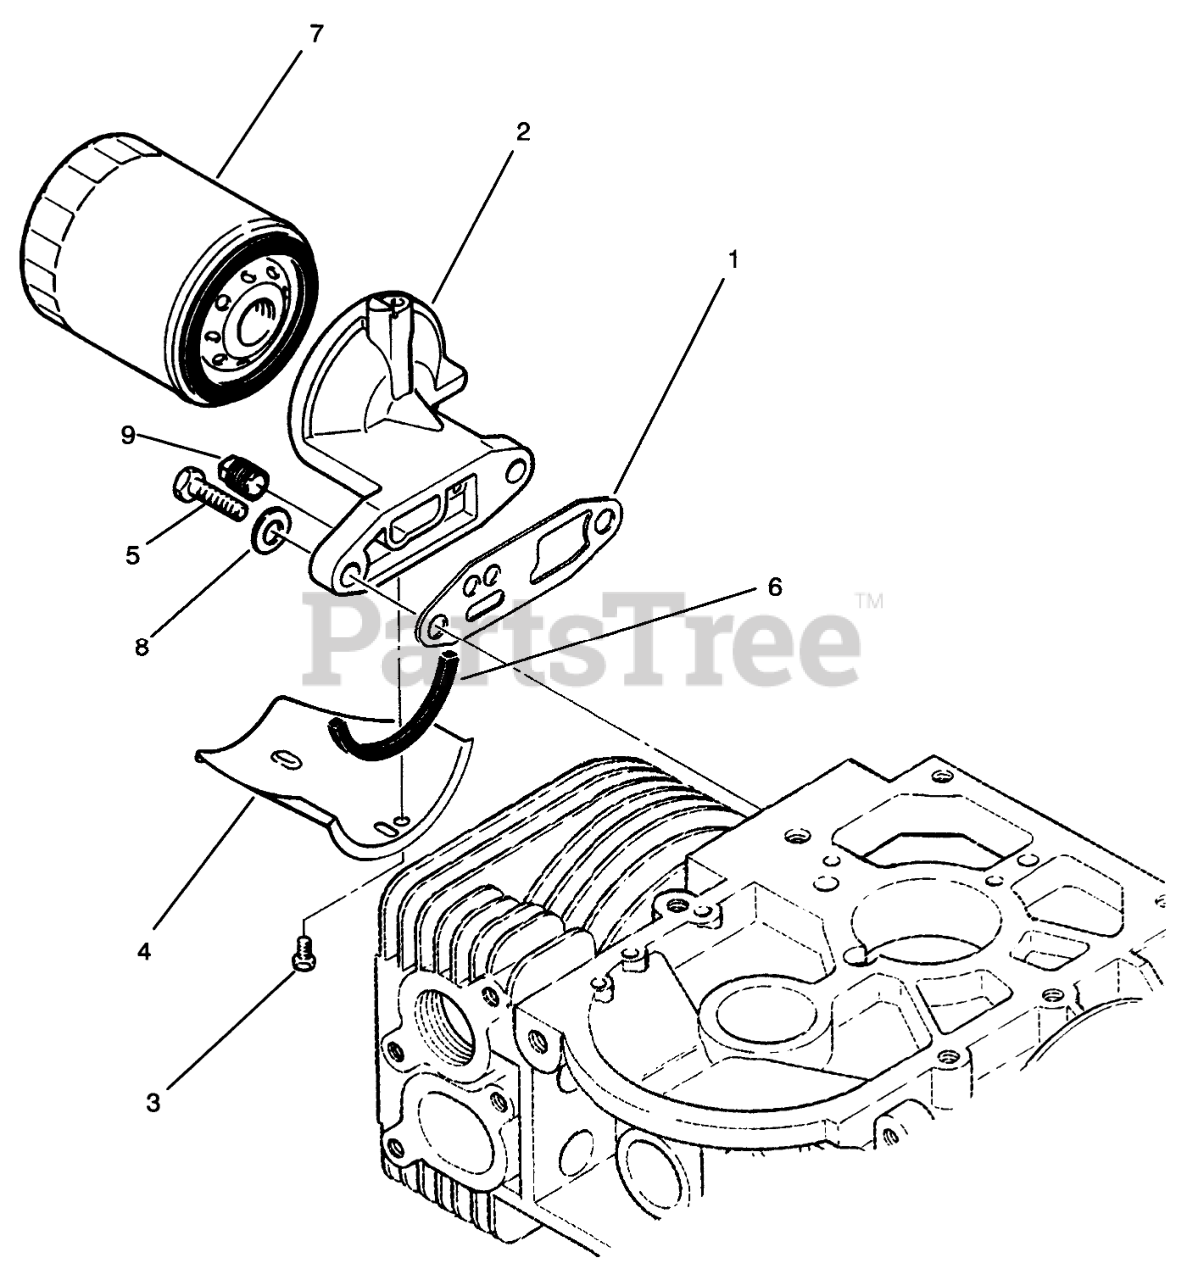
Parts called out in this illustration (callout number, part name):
1	Gasket
2	Adapter
3	Bolt
4	OIL-DRAIN
5	HHCS 5/16-18 X 1
6	OIL-DRAIN SEAL
7	OIL FILTER
8	WASHER
9	Plug
